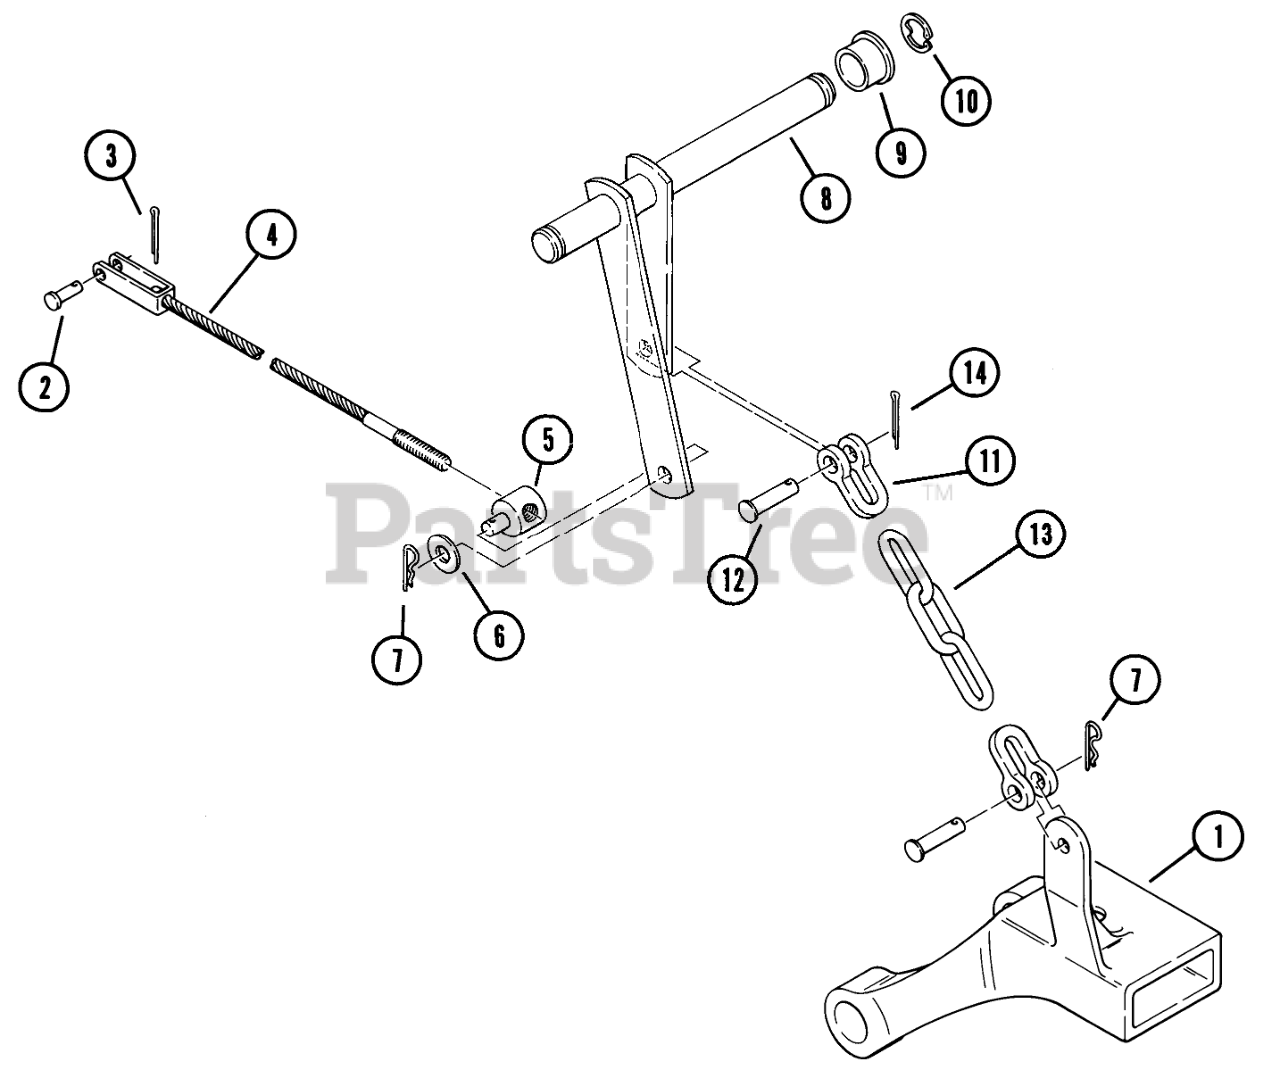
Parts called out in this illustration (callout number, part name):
1	Hitch
2	Pin
3	Cotter Pin
4	ASSY-LIFT CABLE
5	TRUNNION-CLUTCH ROD
6	Washer
7	Hairpin
8	Lever Assy.
9	BUSHING
10	E-RING
11	Clevis
12	Clevis Pin
13	Lift Chain
